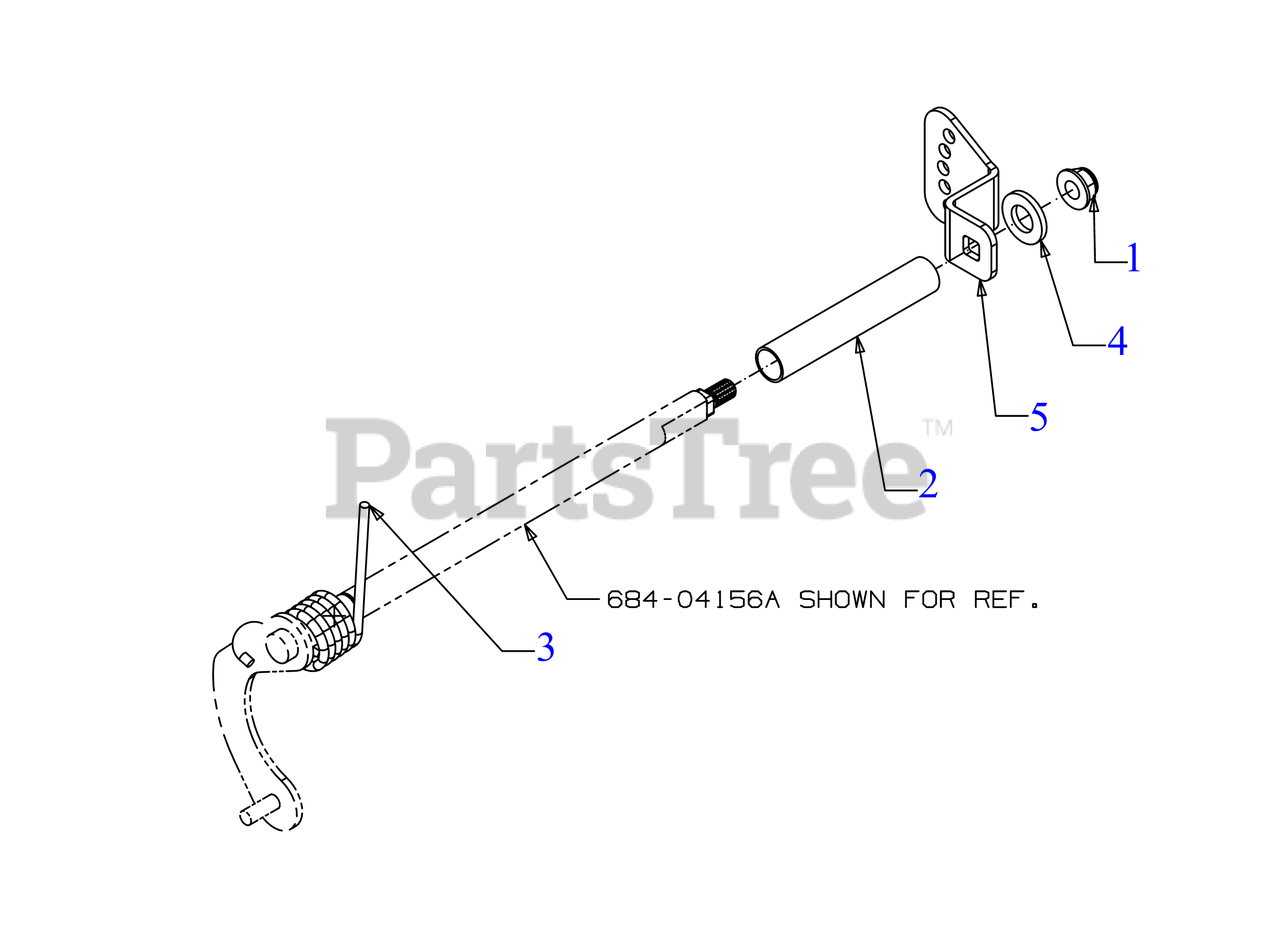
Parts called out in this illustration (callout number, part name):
1	FLANGE LOCK NUT 5/16-18
2	COVER .505 X .635 X 3.64
3	TORSION SPRING
4	FLAT WASHER
5	SPEED SELECT SHIFT BRACKET
